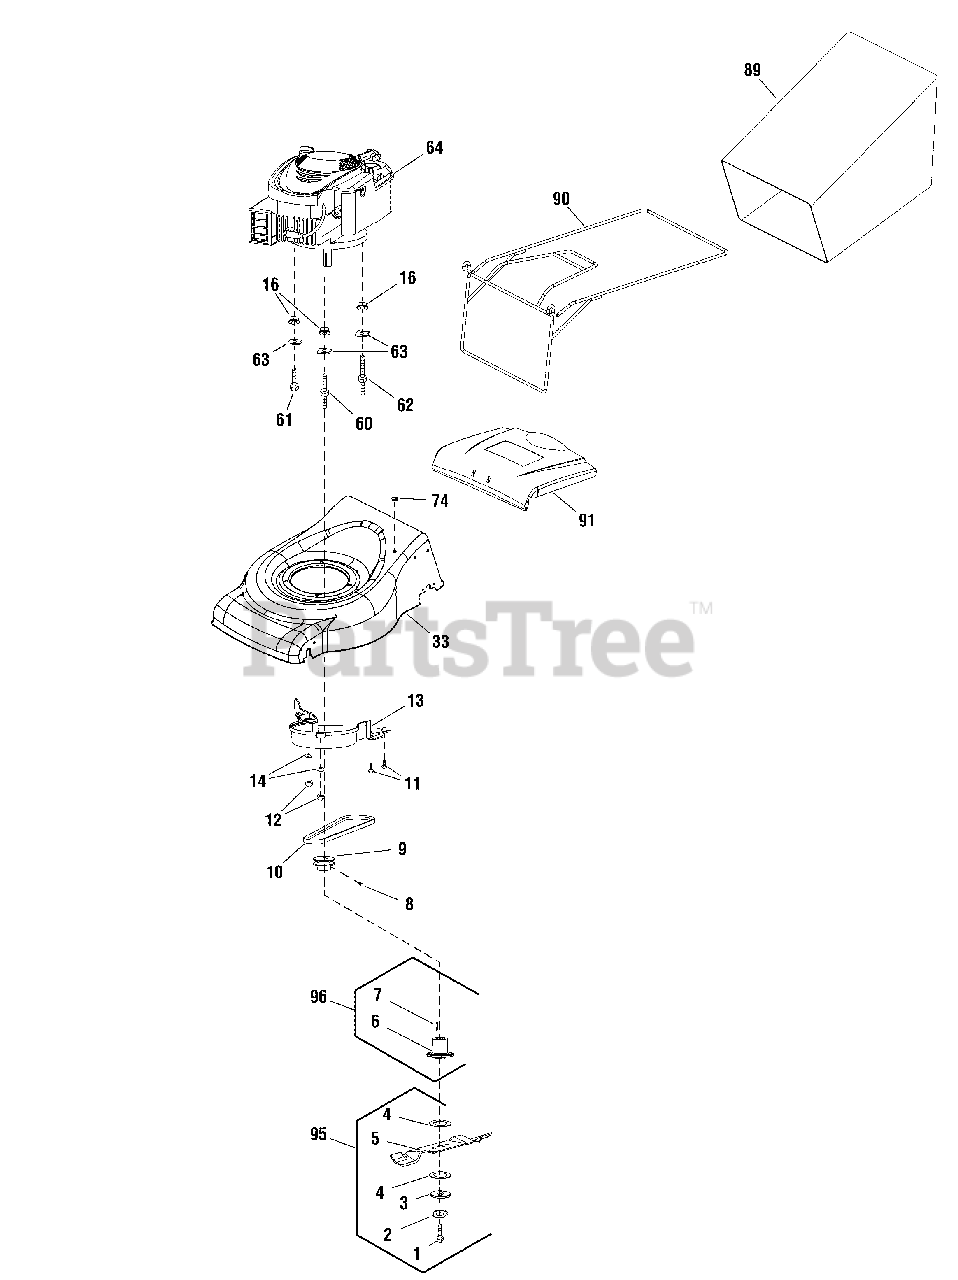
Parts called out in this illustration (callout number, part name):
1	BOLT, Blade
3	PLATE, Blade Support
4	PLATE, Blade
6	SUPPORT, Blade
8	SET SCREW
12	* NUT, Hex Lock
13	COVER, Belt
14	* WASHER, Flat
16	* NUT, Hex Lock
61	* BOLT, Hex
63	WASHER, Square
64	** ENGINE, Briggs & Stratton 650 Series
74	GROMMET
89	BAG, Grass
91	COVER, Rear
95	KIT, Blade
96	KIT, Blade Adapter
